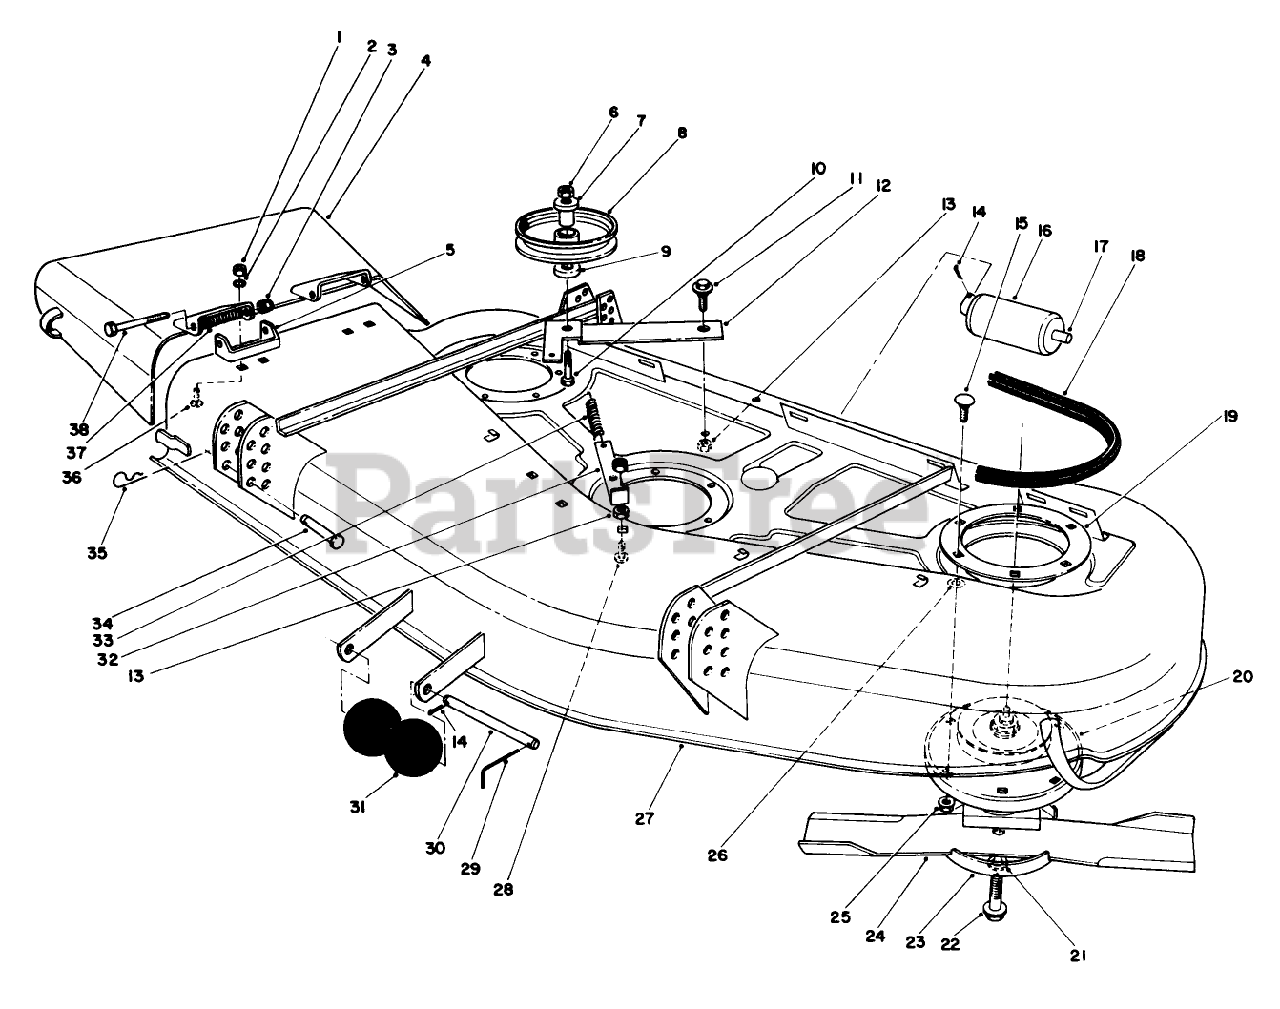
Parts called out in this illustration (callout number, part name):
1	NUT-HEX
2	WASHER-LOCK
3	NUT-HEX
4	DEFLECTOR W/DECALS
5	Bracket-Pivot
6	NUT-HEX
7	BUSHING-PULLEY
8	PULLEY-IDLER
9	WASHER-FLAT
10	SCREW-HH
11	SCREW-SHOULDER
12	Lever-Deck
13	NUT-LOCK, NI
14	PIN-COTTER
15	SCREW-CARR
16	ROLLER-DECK
17	SHAFT-ROLLER, REAR
18	V-BELT, DECK
19	SUPPORT-DECK, RING
20	SPINDLE HSG ASM
21	WASHER-LOCK
22	SCREW-BLADE
23	Cup-Scalp
24	Blade
25	NUT-HF
26	WASHER-FLAT
27	Housing
28	SCREW-CARR
29	PIN-SPECIAL
30	SHAFT-ROLLER
31	ROLLER
32	Anchor-Spring
33	SPRING-EXTENSION, DECK
34	PIN-CLEVIS
35	PIN-HAIR
36	SCREW-CARR
37	SPRING
38	SCREW-HH
